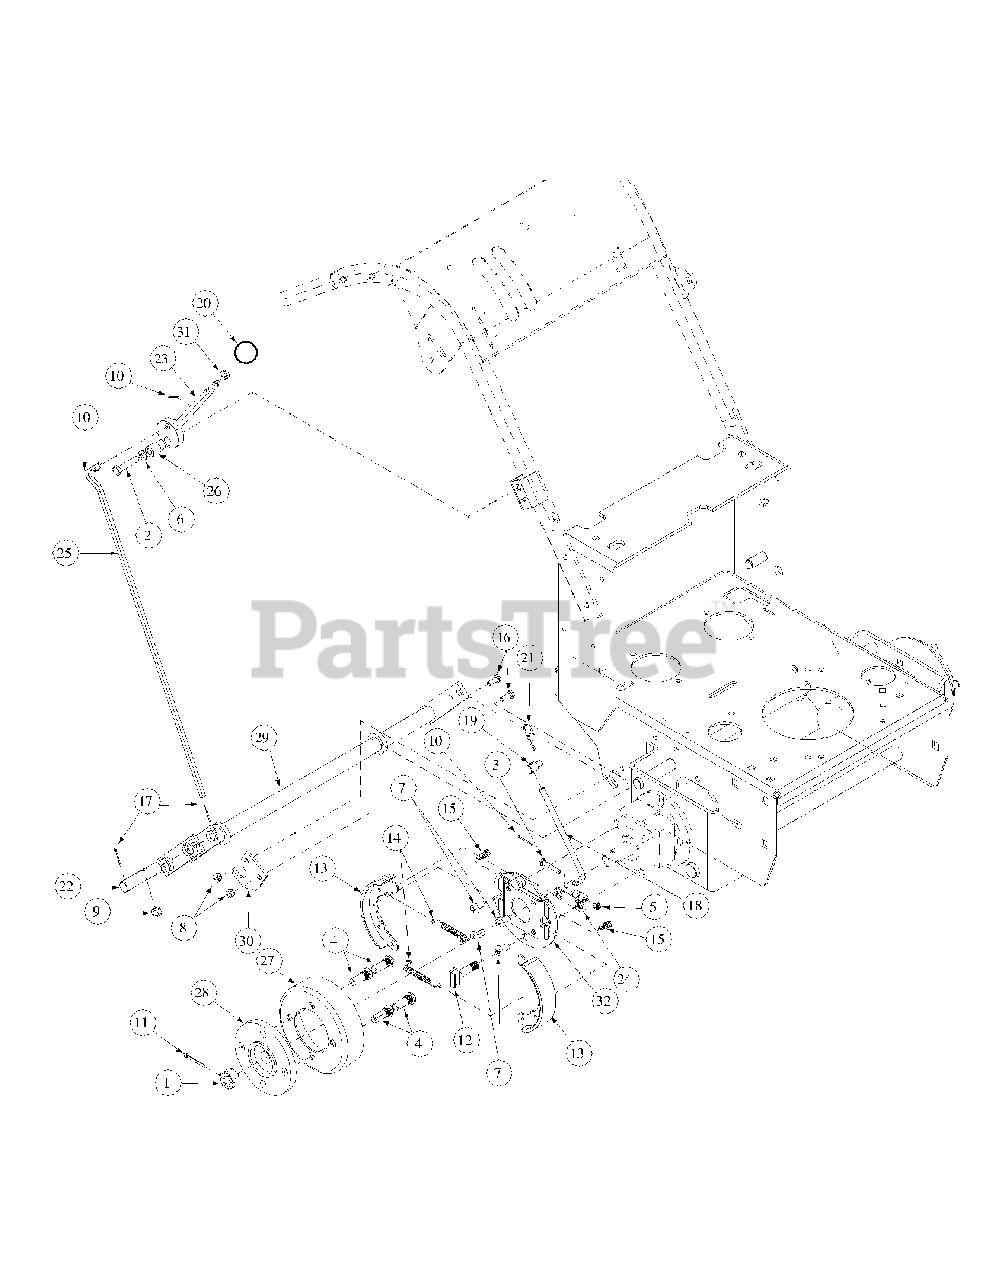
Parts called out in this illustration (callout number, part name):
1	Nut, Castle, 3/4-16
2	Capscrew, 3/8-16 x 1" Grade 5 Zinc
3	Cap Screw, 1/4-20 x 1.50, Grade 5
4	Bolt, Wheel, 1/2-20 x 1-3/8
5	Lock Nut, Nylon Insert, 1/4-20 Grade A
6	Lock Washer, 3/8 Zinc
7	Capscrew, Socket Button Hd., 3/8-16 x 3/4 Zinc
8	Nut, 5/16-18, Nylock
9	Nut, Nylon Insert, 3/8-16 Grade A
10	Cotter Pin, 3/32 x 3/4, Zinc
11	Cotter Pin, 5/32 x 1-1/2 Zinc
12	Brake Cam, Actuating
13	Brake Shoe w/Lining, 6 x 1-1/4
14	Brake Spring, Tension
15	Brake Spring, Anti-Vibration
16	Cap Screw, 5/16-18 x 3/4, Grade 5
17	Cotter Pin, 3/32 x 1, Zinc
18	Brake Rod
19	Swivel Joint
20	Knob, Red, Shift w/Insert
21	Hair Pin, 3/8"-1/2"
22	Joint, Brake Pull
23	Lever Assembly, Brake
24	Brake Clamp, Control Assembly, Hydro
25	Rod, Long Brake, Hydro WB
26	Pivot Spacer, Hydro WB
27	Brake Drum
28	Hub, Wheel Motor
29	Brake Shaft Assembly WT
30	Pivot Mount, Brake
31	Nut, 3/8-16, Jam, Grade 2
32	Brake Backing Plate
